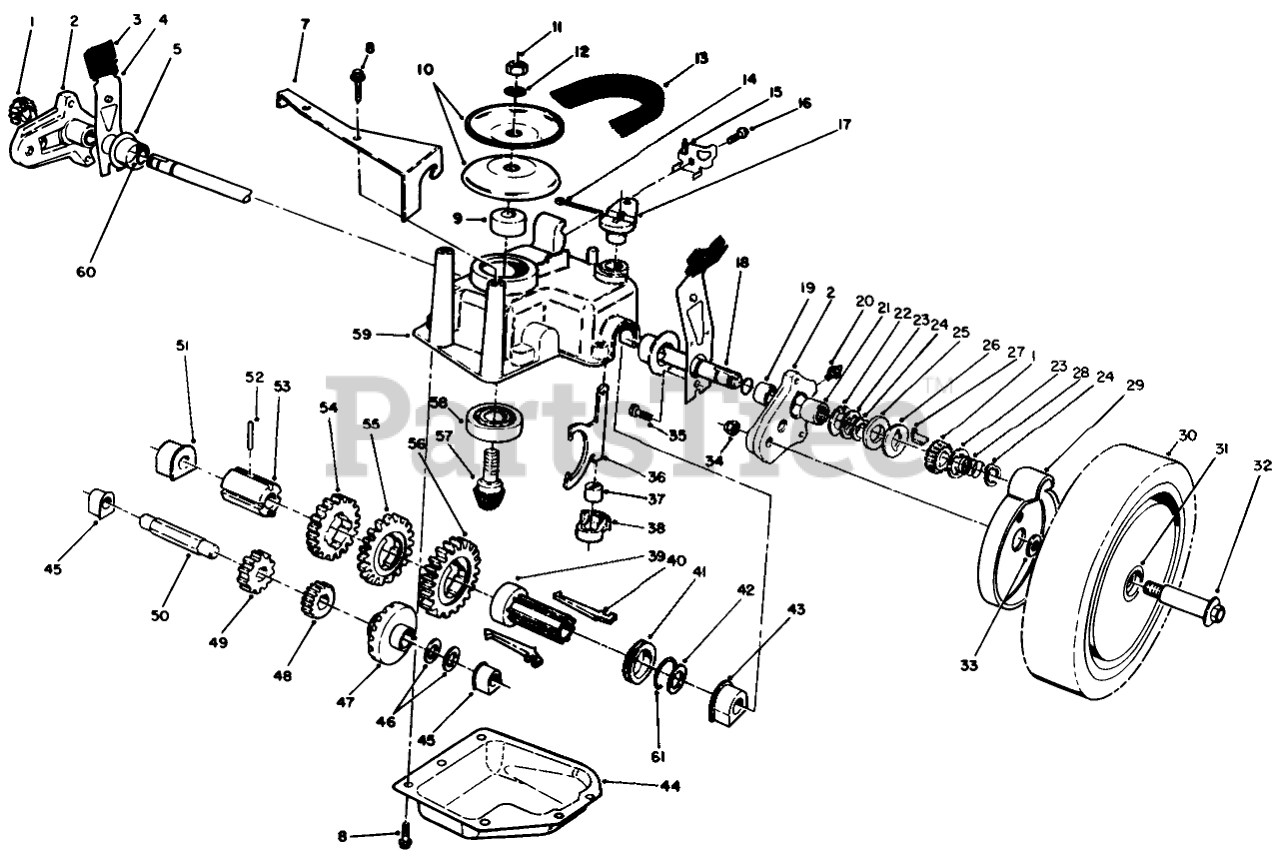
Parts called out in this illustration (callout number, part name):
1	GEAR-PINION
2	Pivot Arm Assembly (Incl. Ref #19, 20, & 21)
3	KNOB-ARM
4	SPRING ARM ASM SP
5	CAP-END
7	Bracket-Guide
8	SCREW-HWHTF
9	SPACER
10	Pulley Half
11	NUT-HEX
12	WASHER-FLAT
13	V-BELT E
14	PIN-COTTER
15	CLAMP-CABLE
16	SCREW-HWHTF
17	LEVER-SHIFT
18	SHAFT-OUTPUT
19	BUSHING
20	FITTING-GREASE
21	BEARING-ROLLER
22	WASHER-ARM, PIVOT
23	WASHER-THRUST, KEYED
24	RING-CLIP, LOCKING
25	RING-FRICTION
26	WASHER-CLUTCH
27	KEY-ROCKING, LH
28	SPRING-COMPRESSION
29	COVER-WHEEL
30	Wheel-Tire & Gear Ass-y (Incl. Ref. #31)
31	BUSHING
32	WHEEL BOLT
33	SPACER-COVER, WHEEL
34	Nut
35	SCREW-HWH
36	YOKE-SHIFT
37	BUSHING-YOKE
38	RETAINER-FORK, SHIFT
39	SLEEVE-KEY, SHIFT
40	KEY-SHIFT
41	COLLAR-SHIFT
42	WASHER-PLAIN
43	BUSHING-OUTPUT
44	Cover-Gearcase
45	BUSHING
46	WASHER-THRUST
47	Gear-Bevel
48	PINION-20T
49	PINION-25T
50	SHAFT-INTERMEDIATE
51	BUSHING
52	PIN-SPRING
53	SLEEVE-GEAR
54	GEAR-39T
55	GEAR-44T
56	GEAR-49T
57	Gear-Pinion
58	BEARING-BALL
59	CASE-GEAR, UPPER
60	O-RING
61	CLIP-SPRING
